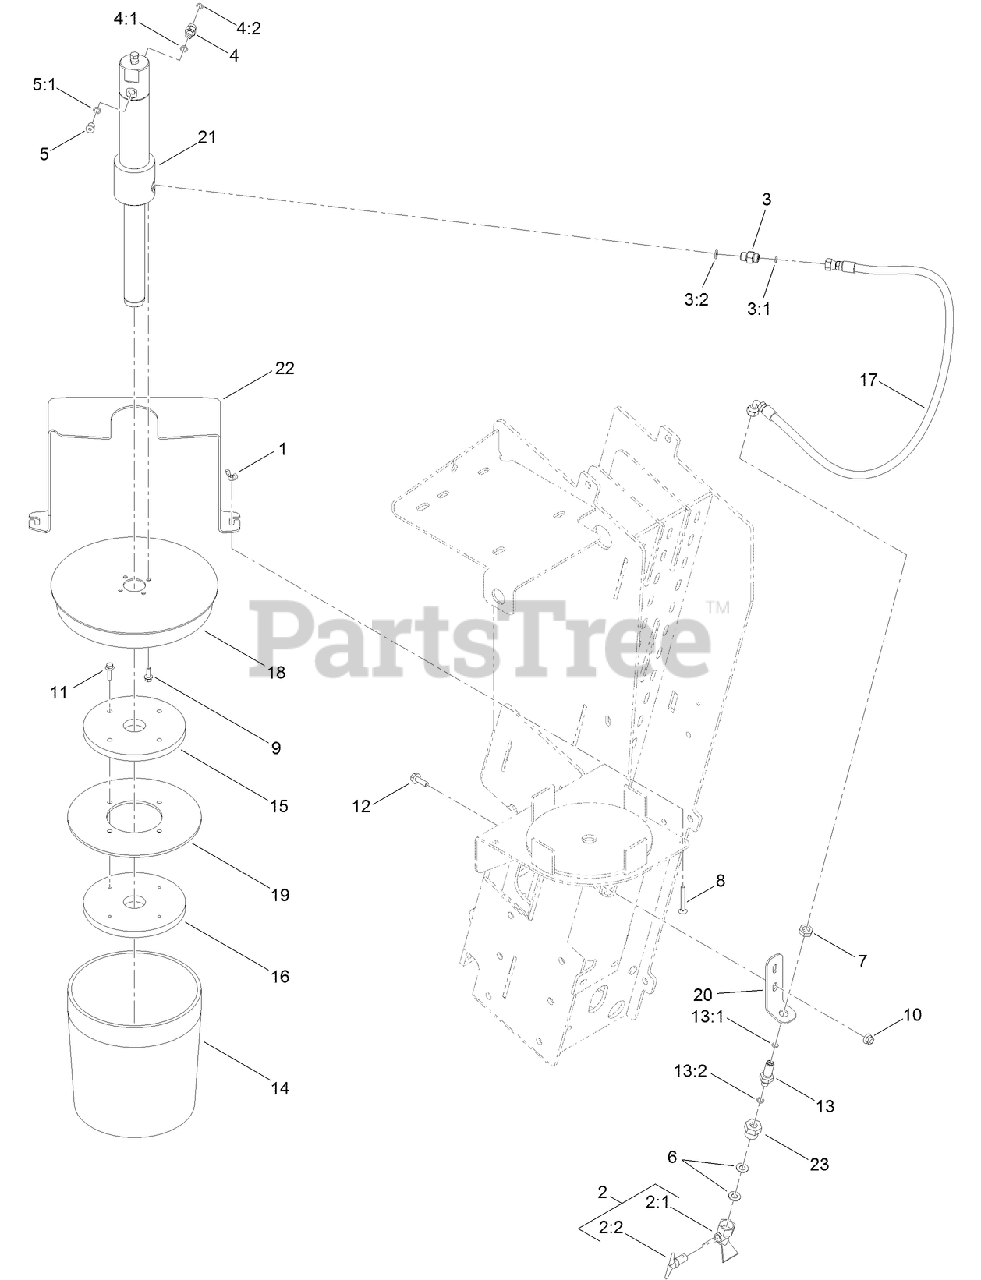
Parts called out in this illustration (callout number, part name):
1	WINGNUT
2	SPRAY NOZZLE ASM
2:1	NOZZLE-SPRAY, AIRLESS
2:2	ORIFICE INSERT ASM
3	FITTING-STRAIGHT
3:1	O-RING
3:2	O-RING
4	FITTING-STRAIGHT
4:1	O-RING
4:2	O-RING
5	PLUG ASM
5:1	O-RING
6	WASHER-FLAT
7	NUT-LOCK
8	SCREW-CARR
9	SCREW-HHF
10	NUT-LOCK, HHF
11	SCREW-HHF
12	SCREW-HHF
13	FITTING-STRAIGHT
13:1	O-RING
13:2	O-RING
14	COMPOUND-THREAD
17	HOSE-HYD
18	COVER-APPLICATOR, LUBE
19	SEAL-RUBBER, FOLLOWER
20	BRACKET-NOZZLE GREASER
21	HYD GREASE PUMP ASM
22	TIEDOWN-COVER, GREASE
23	REDUCER-STRAIGHT, THREADED
